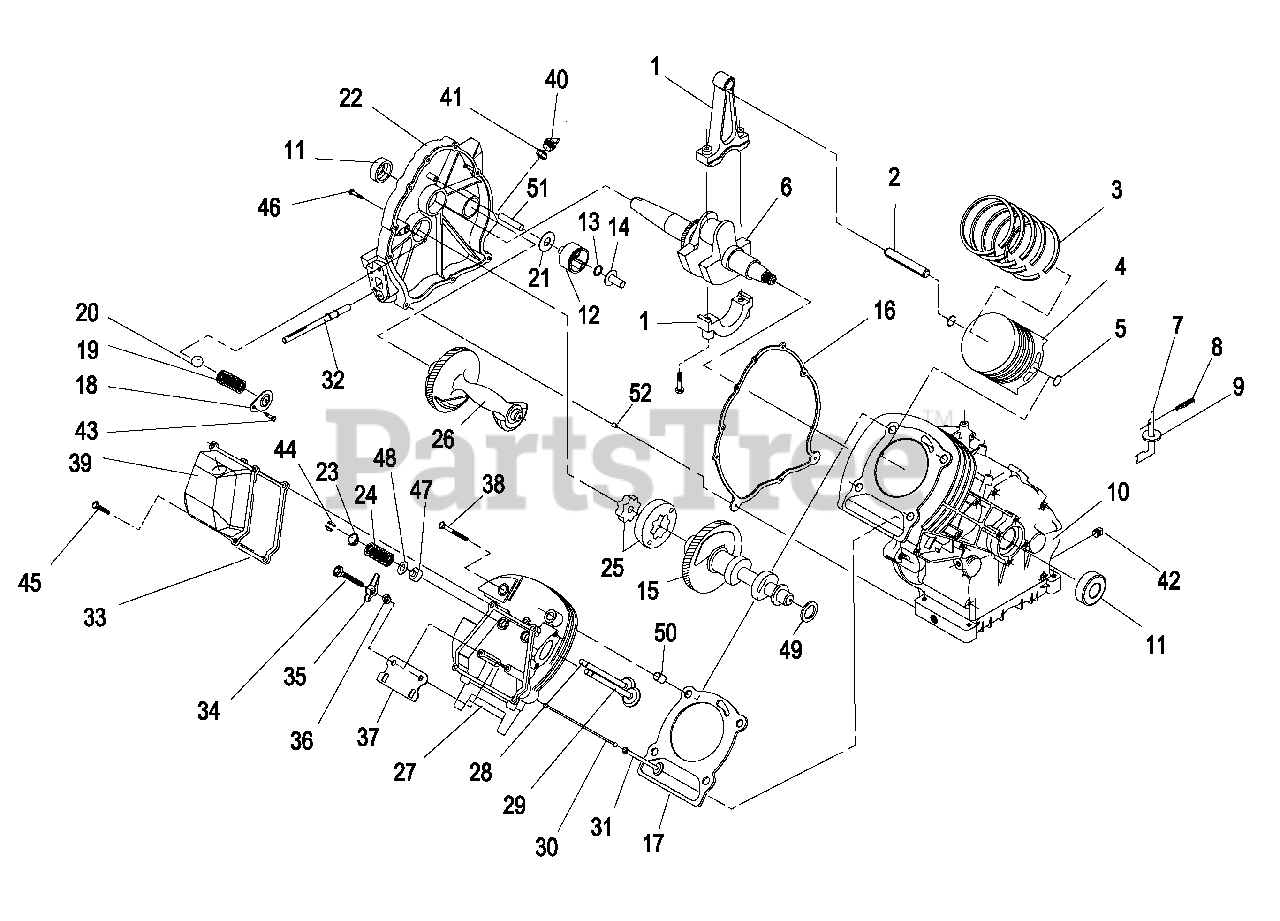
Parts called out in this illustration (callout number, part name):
1	ASSEMBLY, CONNECTING ROD
2	PIN, PISTON D20
3	RING SET, PISTON Ø90
4	PISTON, FLAT TOP Ø90 COATED
5	RETAINER, PISTON PIN 20
6	ASSEMBLY, CRANKSHAFT GH410 SMALL TAPER
7	ARM, GOVERNOR RC45
8	PIN, "R" GOVERNOR ARM
9	WASHER, GOVERNOR ARM THRUST
10	CRANKCASE, SUBASSEMBLY WITH PLUGS GH410
11	SEAL, 35 I.D. CRANKSHAFT
12	ASSEMBLY, GOVERNOR GEAR
13	C-RING, GOVERNOR GEAR RETAINER
14	SPOOL, GOVERNOR- MACHINE
15	ASSEMBLY, CAMSHAFT & GEAR
16	GASKET , CRANKCASE
17	GASKET, HEAD 410
18	COVER, OIL PRESSURE RELIEF
19	SPRING, OIL RELIEF 360
20	BALL, DIA 11/32 PRESSURE RELIEF
21	WASHER, THRUST GOVERNOR GEAR
22	ASSEMBLY, COVER, GEAR TOP CHECK / FILL
23	RETAINER, VALVE SPRING
24	VALVE SPRING LF
25	SET,GEROTOR 12 THK
26	BALANCER
27	ASSEMBLY,CYLINDER HEAD SEATS & GUIDES
28	VALVE, EXHAUST
29	VALVE, INTAKE
30	PUSH ROD 174.9
31	TAPPET
32	ASSEMBLY, SCREEN OIL PICK-UP
33	GASKET, ROCKER COVER 410
34	STUD, D20 PIVOT BALL
35	ROCKER ARM
36	NUT, JAM (ROCKER ARM)
37	PLATE, PUSH ROD GUIDE
38	SCREW, HHFL M10-1.5 X 105
39	ASSEMBLY, ROCKER COVER GENERAC TEXT
40	PLUG, OIL FILL PLASTIC
41	O-RING 17.8 I.D. x 2.4
42	PLUG, STANDARD PIPE 3/8 STEEL SQUARE HEAD
43	SCREW, TAPTITE M5-0.8 X 10 BP
44	KEEPER, VALVE SPRING
45	SCREW & LOCKWASHER M6-1 X 12
46	SCREW, HHFC M8-1.25 X 42
47	SEAL, VALVE STEM D7
48	WASHER, VALVE SPRING
49	WASHER, LARGE SPRING
50	SLEEVE, DOWEL PIN 14 DIA.
51	SHAFT, GOVERNOR RC55
52	SLEEVE, DOWEL PIN 12 DIA.
